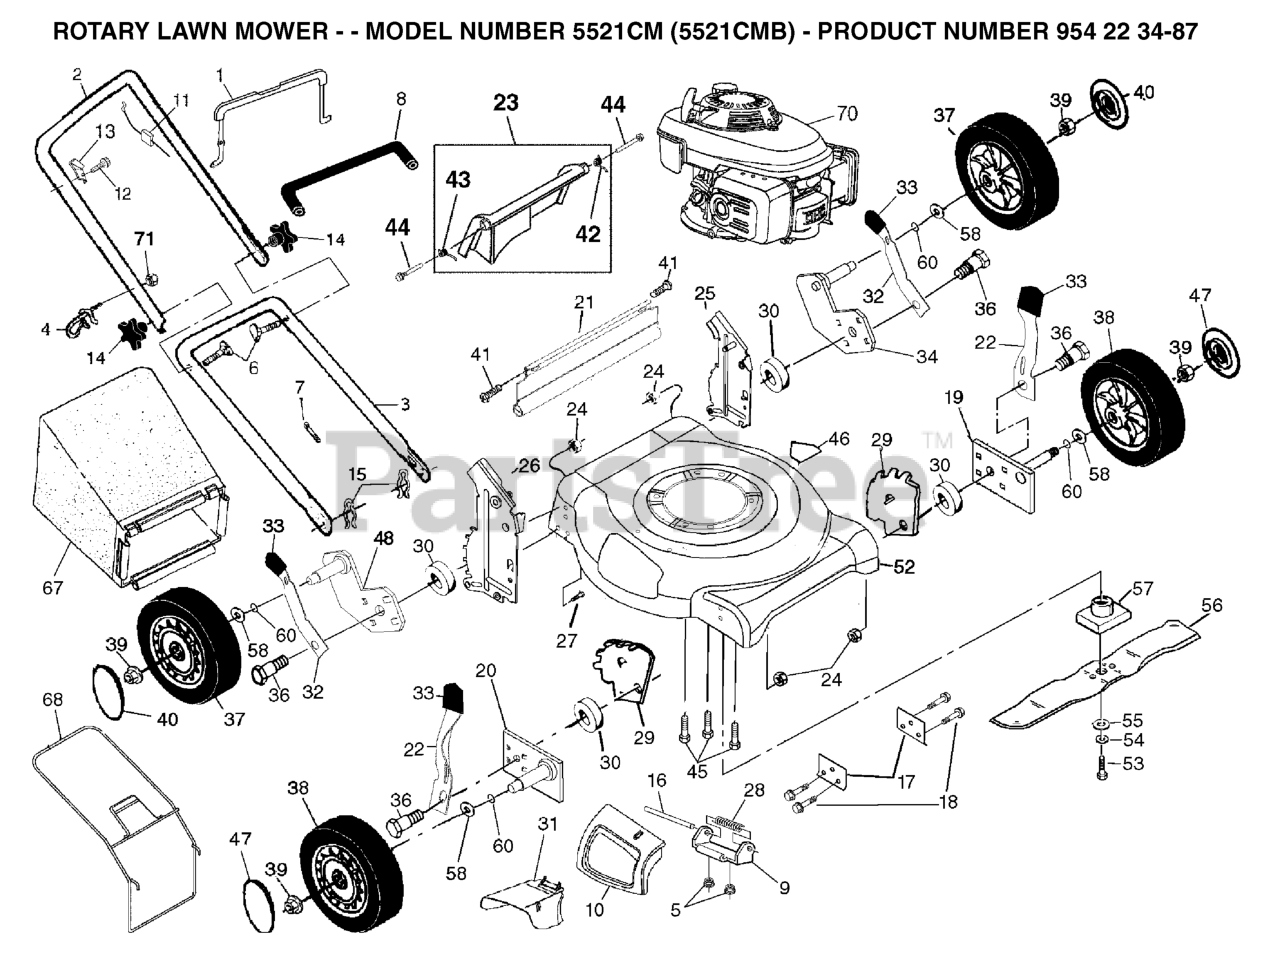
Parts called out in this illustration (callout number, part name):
3	HANDLE.LOWER.GREY
4	ROPE, GUIDE
5	LOCKNUT.NYLOC.1/4-20
6	HANDLE BOLT
7	TIE GUIDE
8	GRIP.HANDLE.FOAM
9	BRACKET.ASM.HOUSING.EZ.MUL
11	ENGINE ZONE CONTROL CABLE
13	BRACKET
14	KNOB.HANDLE.STAR.HUSQ.GRAY
15	HAIRPIN COTTER
16	ROD.HINGE.COMBI-C
17	SUPPORT BRACKET
18	SCREW 1/4X20
19	AXLE ARM ASSY LF
20	AXLE ARM ASSY
21	REAR DEFLECTOR, POULAN PR6N22
22	REPL BY 532 1683-60
23	KIT.REAR.DOOR.21.DOMED.
24	NUT.CENTERLOCK.5/16-
25	HANDLE BRACKET ASSEMBLY, LEFT
26	HANDLE.BRKT.ASSY.RIGHT.BLACK
27	SCREW
28	TORSION SPRING
29	WHEEL BRACKET ADJUSTER
30	SPACER.34X1.38X.22
31	DEFLECTOR.CLIPPING.21.GREY
36	SHOULDER BOLT
37	WHEEL.10X2.PR.HITRAC.BLACK
38	WHEEL 8 X 2 BLACK BALL BEARING
39	HEX FLANGE LOCKNT
41	HINGE SCREW
42	SPRING (LH)
43	SPRING (RH)
45	BOLT 3/8-16X1-1/8
46	DECAL HYT
47	HUBCAP
52	HOUSING ASSEMBLY
53	SCREW, HEX HD 3/8-24 X 1-3/8
54	LOCKWASHER
55	WASHER,HARDEN
56	BLADE
57	BLADE ADAPTER
58	WASHER.FLAT.1/2
60	O-RING
67	GRASS BAG
68	CATCHER FRAME
